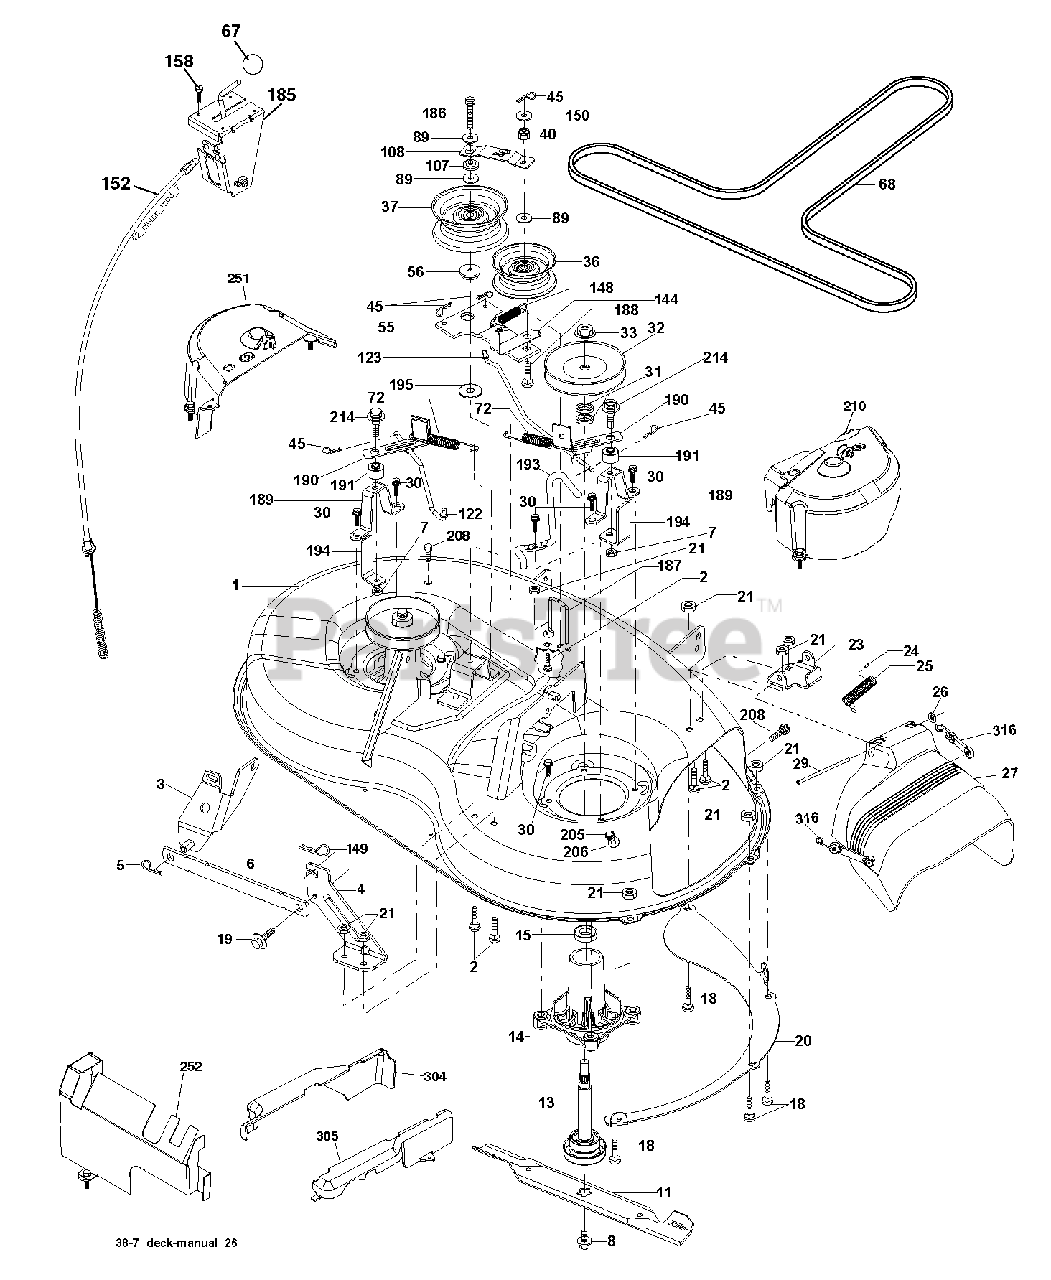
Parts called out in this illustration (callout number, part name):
1	DECK.WELDMENT.38"2005
2	BOLT
3	BRKT ASM SWAY BAR
4	BRACKET DECK SWAY BAR 38"/42"
5	RETAINER-SPRNG RB
6	BAR SWAY DECK
7	NUT.71038.31-18.HEX.NYLOCK
8	BOLT.WASHER.ASM.7/16-2
11	BLADE 38" PREMIUM
13	SHAFT.ASM.MDRL.N/GREASE.38
14	HOUSING MANDREL
18	BOLT
19	BOLT SHD 5/16-18
20	BAFFLE VORTEX
21	LOCKNUT
23	BRKT.DEFLECTOR.38"2005+
24	CAP-SLEEVE LT
25	SPRING.TORSION.DEFLECT
26	NUT PUSH M
29	ROD.HINGE
30	SCREW, WASHER HEAD
31	WASHER.SPACER.MANDREL
32	PULLEY MANDREL
33	NUT.FLANGE.LOCK.TOP
36	FLAT IDLER PULLEY
37	PULLEY.IDLER.FLAT.UNPLATED
40	LOCKNUT
45	RETAINER M
55	IDLER ARM
56	SPACER.RETAINER.MOWER
67	KNOB T (3/8 HOLE)
68	V-BELT.MOWER.38"2005+
72	SPRING.BRAKE.RETURN.38"
89	WASHER
107	SPACER.IDLER.ARM
108	STIFFENER.IDLER.ARM
122	ROD, BRAKE LH LINK
123	LINK.BRAKE.38"RIGHT
144	KEEPER BELT
148	IDLER RETURN SPRING
149	SPRING.RETAINER.YELLOW.ZINC
150	WASHER LT
152	CABLE.CLUTCH.38".SERVICE
158	SCREW
185	HEAD ASM. CABLE CLUTCH
186	SCREW.HXWSH.3/8
187	KEEPER BELT
188	BOLT, CARRIAGE IDLER
189	STAND, BRAKE
190	ARM, BRAKE
191	SPACER, BRAKE
193	KEEPER BELT RH MANDREL
194	GUARD BRAKE
195	WASHER 12/32X2X10GA
205	SCREW
208	SCREW 3/8-16X1/2
214	BOLT/WASHER ASM 5/16-18
